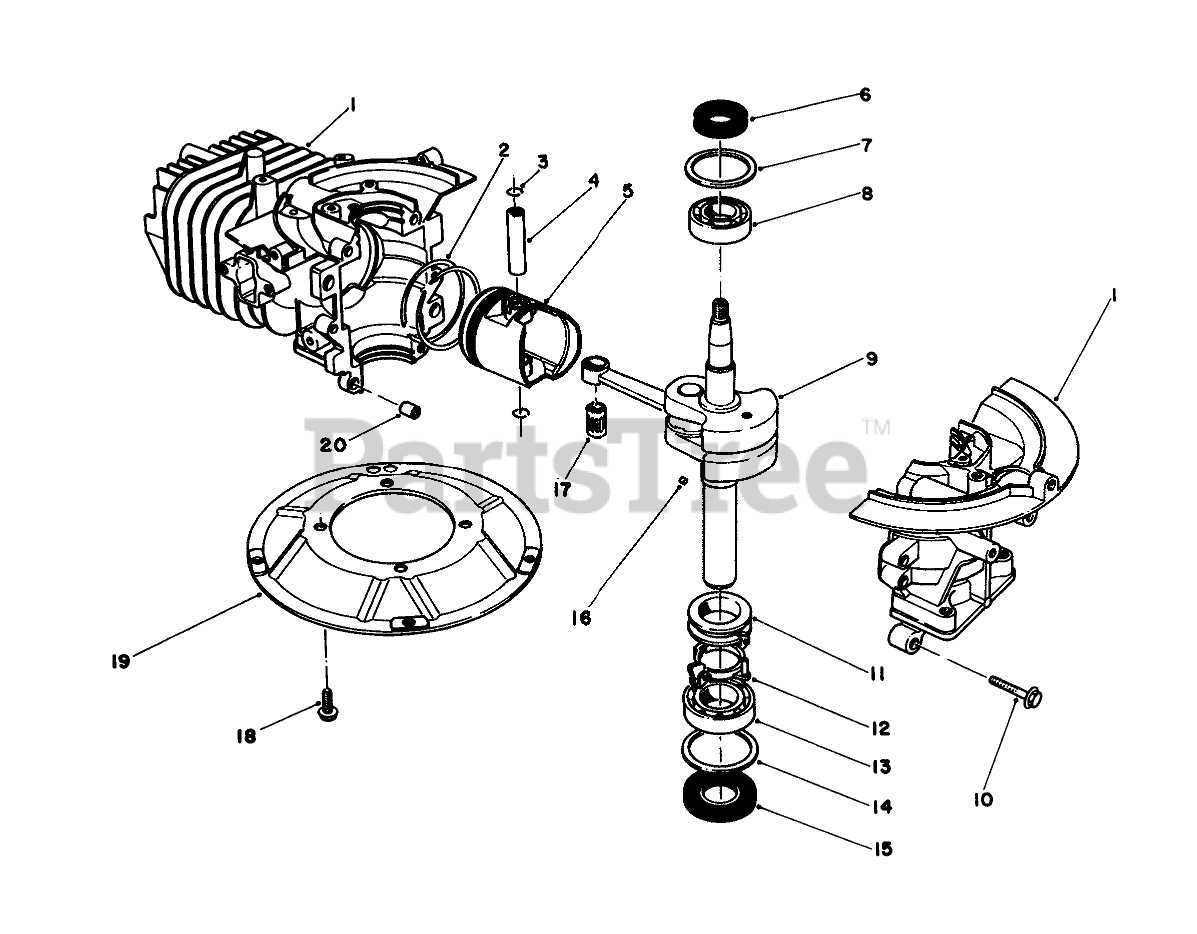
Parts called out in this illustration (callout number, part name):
1	Crankcase-Cylinder Assy.
2	RING SET
3	FLYWHEEL
4	PIN-PISTON
5	Piston (58 mm)
6	OIL SEAL
7	WASHER-UPPER
8	BEARING-UPPER
9	CRANKSHAFT ASM
11	SPACER
12	BRACKET
13	LOWER BRG
14	WASHER-LOWER
15	SEAL-OIL
17	BEARING
19	Plate-Mounting
